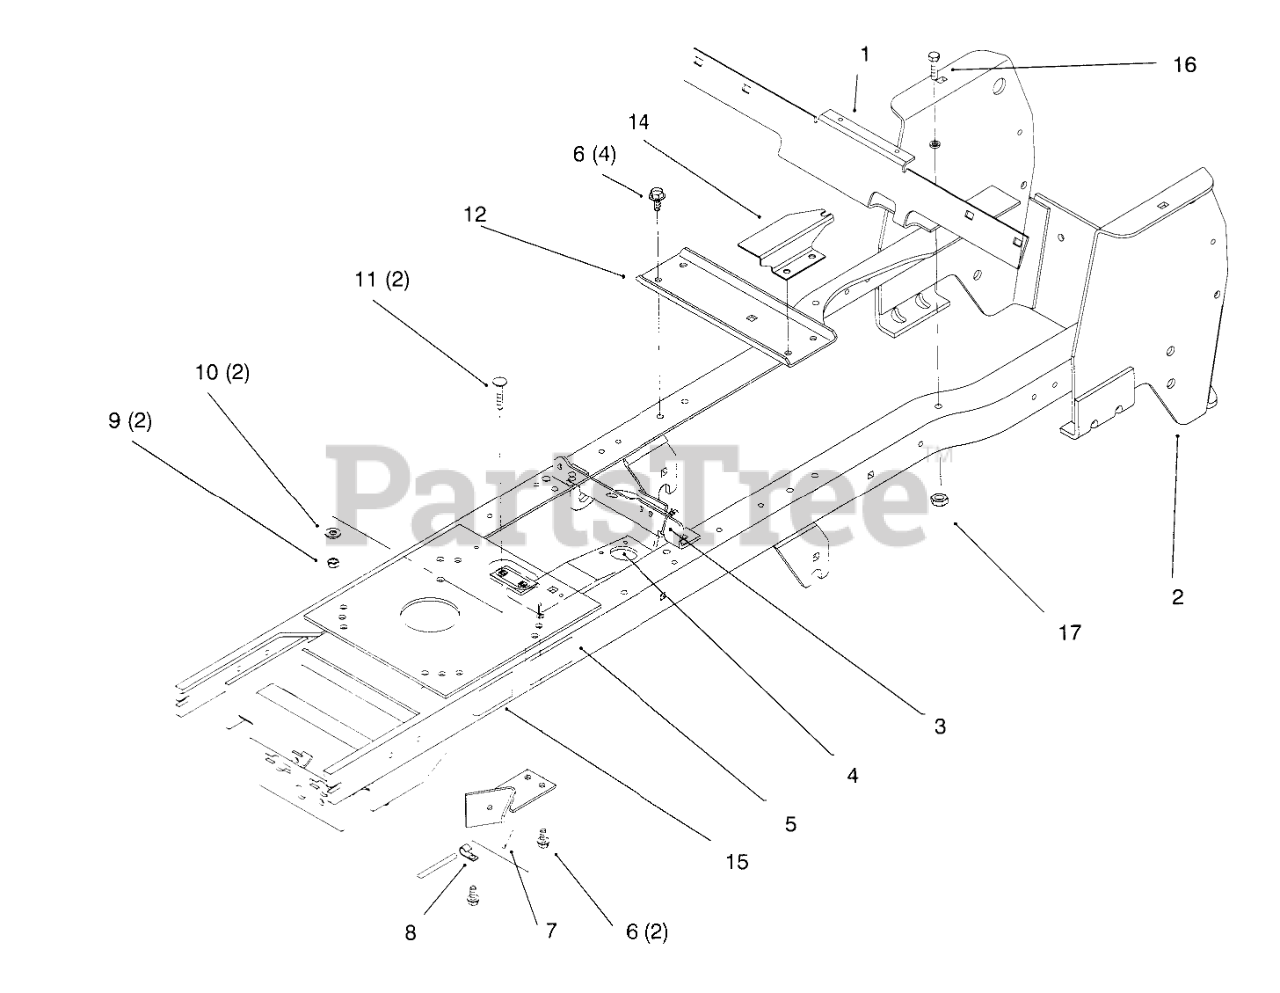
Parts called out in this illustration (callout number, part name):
1	SUPPORT - FENDER
2	Frame W.a.
3	TIE-CABLE
4	STEERING BRKT WA
5	Decal-Belt Install (Only On: 72042,72043)
5	Decal-Belt Install (Only On: 72062,72063,72103)
6	SCREW-HWHTF
7	WLDMT-PTO STOP
8	CLIP
9	NUT-LOCK, NI
10	WASHER-PLAIN
11	BOLT-CARR
12	BRACKET-IDLER PLATE
14	BRACKET-HOC GAGE
15	Screw-HH (Only On: 72043,72063,72103)
15	DECAL-ATTACH A-MATIC
16	Screw-HH (Only On: 72043,72063,72103)
17	Nut-Lock (Only On: 72043,72063,72103)
